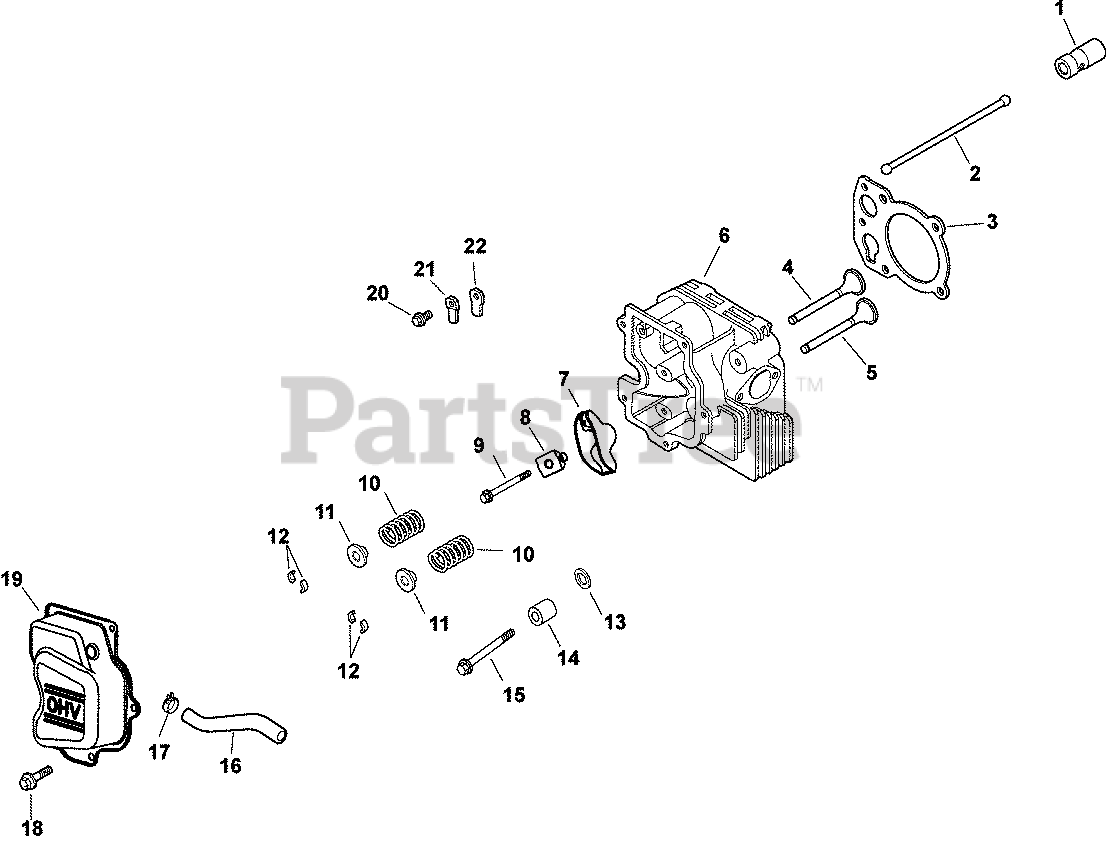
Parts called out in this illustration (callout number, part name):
1	LIFTER, HYDRAULIC VALVE-USE 25 351 10-S
2	ROD, PUSH
3	GASKET, CYLINDER HEAD
4	VALVE, EXHAUST
5	VALVE, INTAKE
6	KIT, HEAD, CYLINDER
7	ARM, ROCKER
8	PIVOT, ROCKER ARM
9	SCREW, FLG M6X1.0X34
10	SPRING, VALVE
11	RETAINER, VALVE SPRING - USE 25 173 28-S
12	KIT, RETAINER
13	WASHER, FLAT 13/32"
14	SPACER, HEAD BOLT EXHAUST PORT
15	SCREW, CYLINDER HEAD (M10 X 80)
16	HOSE, BREATHER
17	CLAMP, HOSE (KM)-USE 25 237 31-S
18	SCREW,FLG THD FRM M6X1.0X16-(#25086397S)
19	COVER, ROCKER
20	SCREW, FLG THD FRM M5X.8X10
21	RETAINER, REED
22	REED, BREATHER
